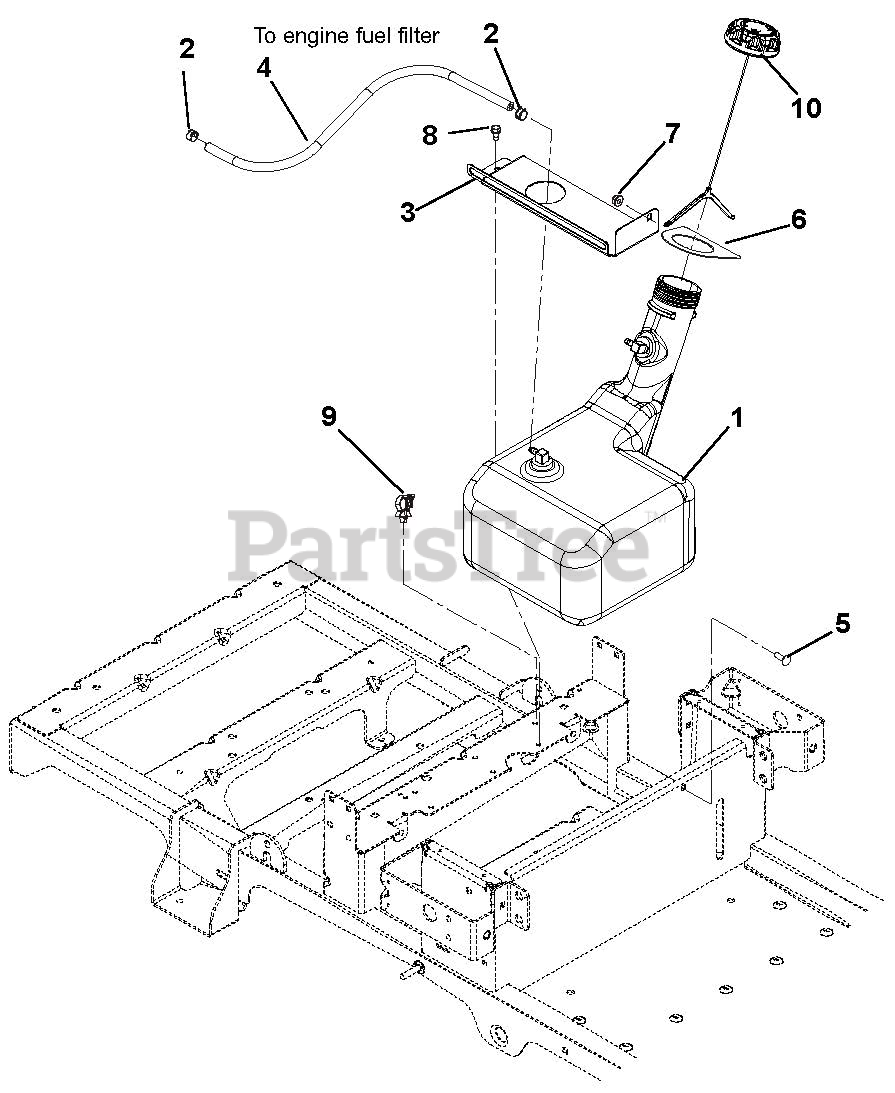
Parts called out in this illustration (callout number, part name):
1	Fuel Tank Subassembly
2	Clamp, Fuel Line
3	Bracket, Tank Strap
4	Hose, .25 Low Perm Gas
5	Bolt, Round Head Square Neck .25-20 x .75
6	Seal, Tank Neck
7	Nut, .25-20 Nyloc Flange
8	Screw, Tapping .25-20 x .50 Hex Washer Head
9	Wire Clip
10	Cap, Fuel Vent-In 2.25"
